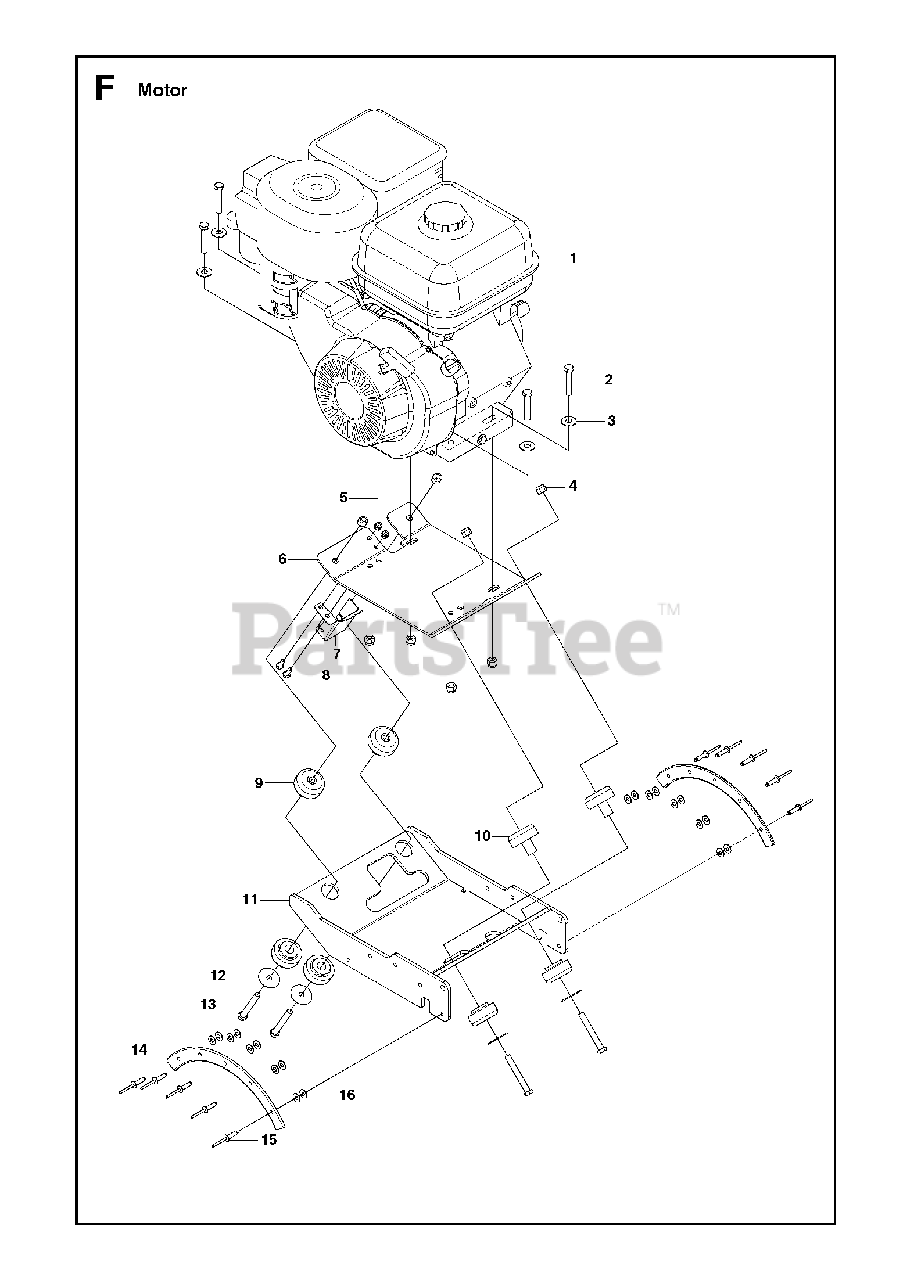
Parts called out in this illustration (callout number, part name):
4	NUT
5	NUT
16	WASHER 1/4 SAE
